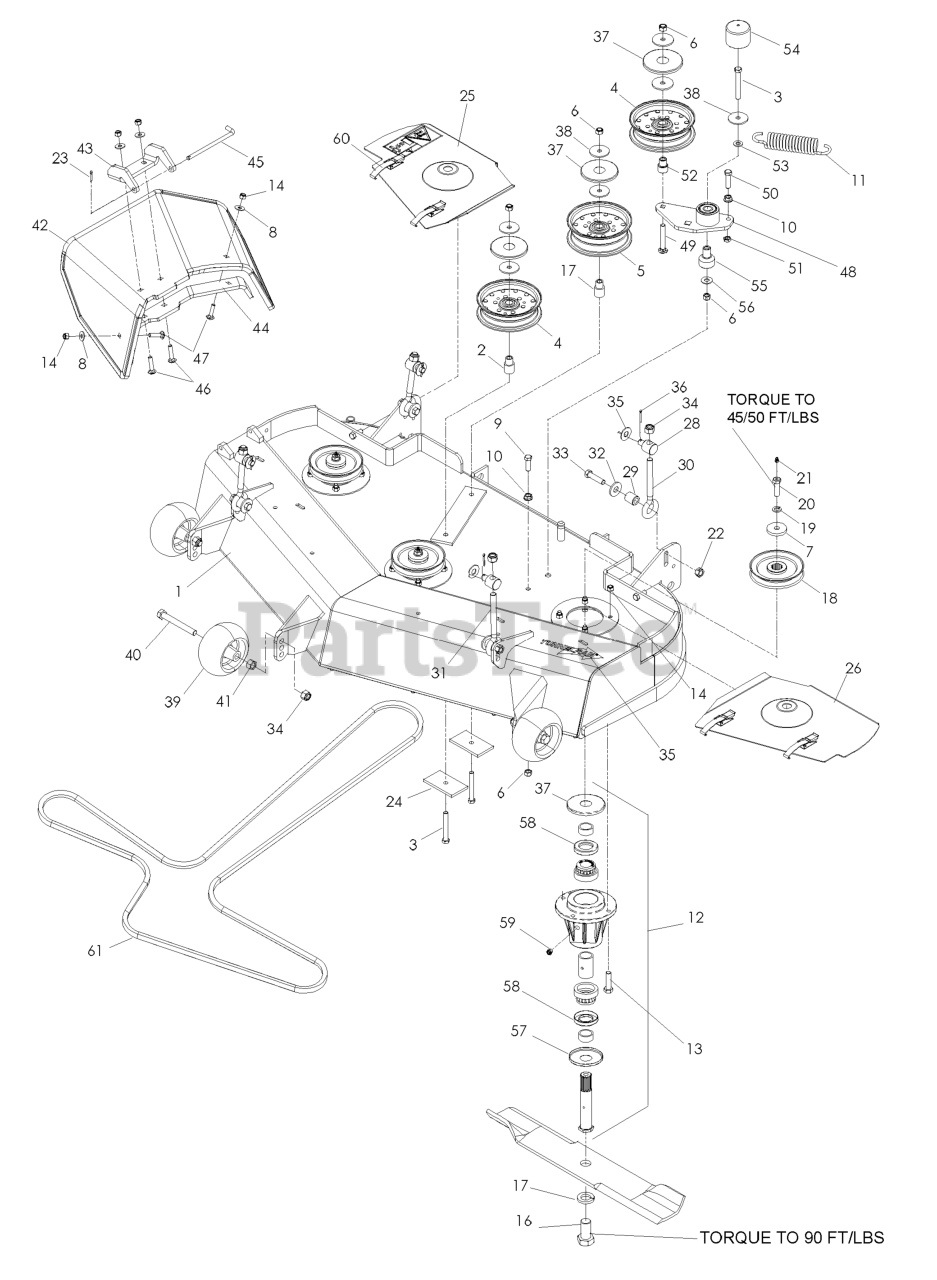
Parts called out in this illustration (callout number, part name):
1	DECK W/DECALS 48" HUS
2	IDLER BUSHING
3	HCS 3/8C X 3
4	IDLER PULLEY
5	IDLER PULLEY (TALL)
6	NUT 3/8-16 NYLOC
7	SPINDLE WASHER
8	WASHER 5/16 FLAT
9	HCS 3/8C X 1 1/4 GR5
10	NUT 3/8C WHIZ
12	HOUSING ASM, 52/61
13	HCS 5/16C X 1 1/4
14	NUT 5/16 NYLOC
15	BLADE OEM 16 1/4"
16	HCS 5/8F X 1 1/4
17	LOCKWASHER 5/8
18	PULLEY 42-48
19	WASHER 7/16 LOCK
20	HCS 7/16-20 GD 8 SPEC
21	ZERK
22	NUT 7/16C CENTERLOCK
23	RP_COTTER PIN 1/8 X 3/4
24	SUPPORT PLATE
25	48 BELT SHIELD ASM - RH
26	48 BELT SHIELD ASM - LH
27	DECAL, TUNNEL RAM 6"
31	EYEBOLT, 1/2-13 X 5.88
32	WASH USS FLAT 1/2
33	HCS 7/16 - 14 X 1 3/4
34	NUT 1/2-13 HEX NYLOC ZD
35	WASHER 1/2 FLAT
36	PIN COTTER 1/8 X 1 ZD
37	TOP DUST CAP
38	WASHER, 3/8 SPEC
39	GAUGE WHEEL
40	HHB, 1/2-13X4
41	NUT HEX 1/2
42	CHUTE, RUBBER DISCHARGE 42/48"
43	PIVOT BRACKET - RUBBER CHUTE
44	BRACKET, REINF-CHUTE
45	PIN, CHUTE PIVOT
46	RHSNB 5/16-18 X 1-1/2 GR 5 ZD
47	BOLT, CARRIAGE 5/16X1-1/4
48	ARM-IDLER W/BRG
49	RHSNB 3/8-16 X 2.75
50	HCS 3/8-16 X 1-1/2
51	NUT 3/8-16 HEX JAM
52	BUSHING, IDLER
53	WASHER 3/8 SAE FLAT
54	CAP, VINYL
55	PIVOT, BEARING
56	WASHER 3/8 FLAT
57	BOTTOM DUST CAP
58	SHAFT SEAL
59	PLUG-VENTED
60	DRAW LATCH
61	BELT, DECK 48"
